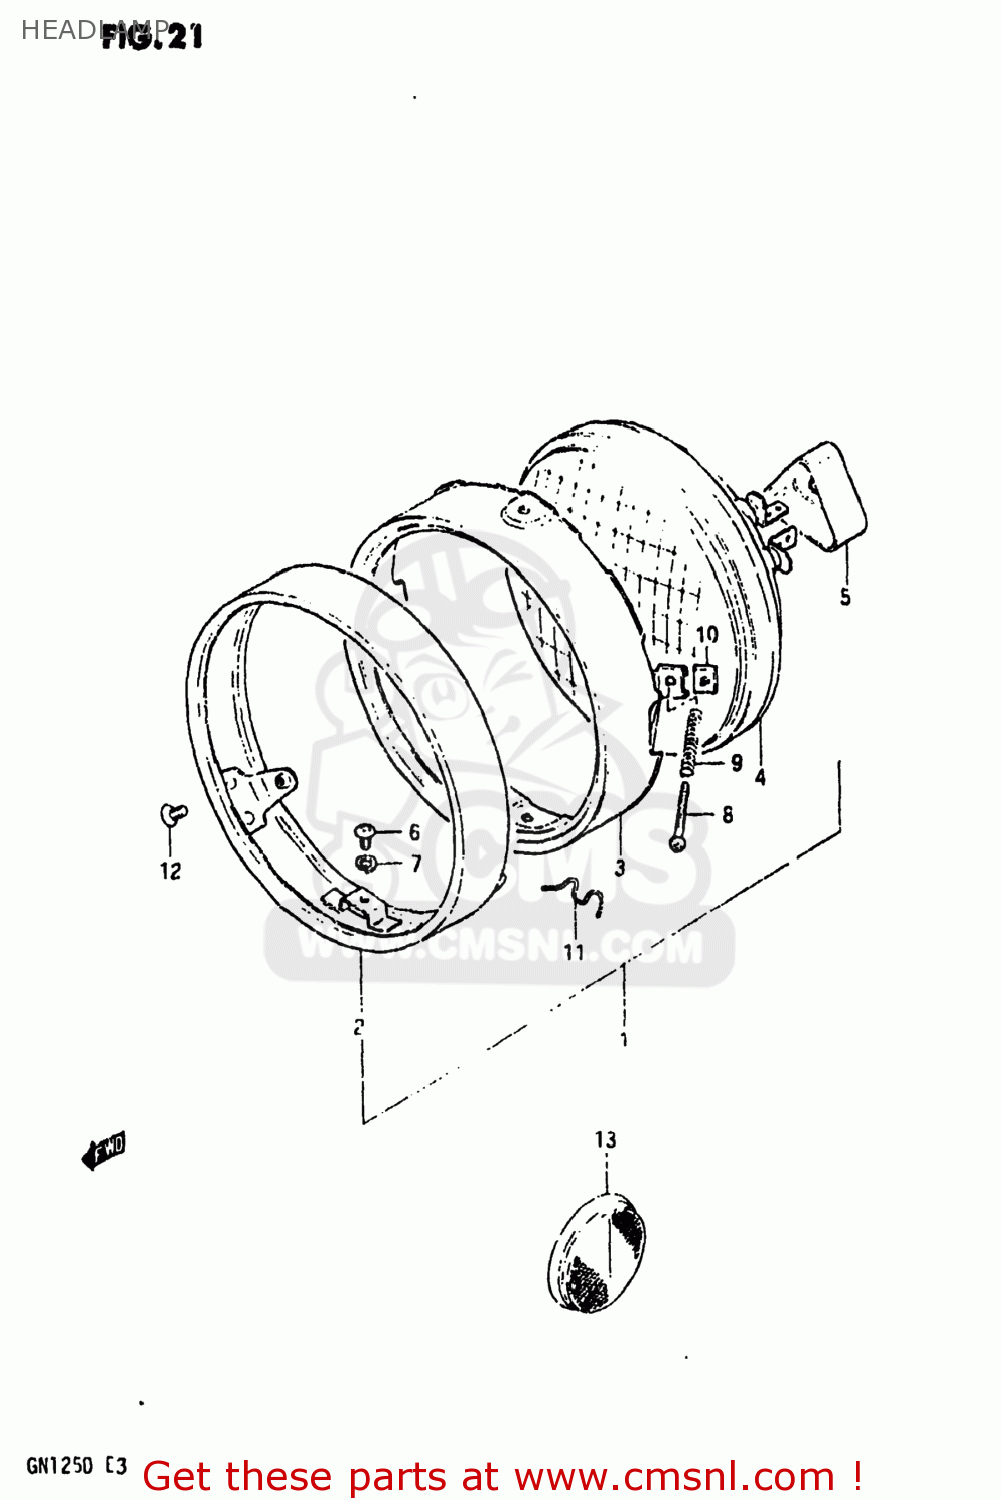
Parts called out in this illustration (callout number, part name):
1	LAMP ASSEMBLY,HEAD
2	RIM
3	RETAINER
4	LAMP UNIT
5	COVER
6	SCREW
7	LOCK WASHER
8	SCREW
9	SPRING
10	NUT
11	SPRING,HEAD LAMP UNIT
12	SCREW(5X12)
13	REFLEX REFLECTOR,RR
